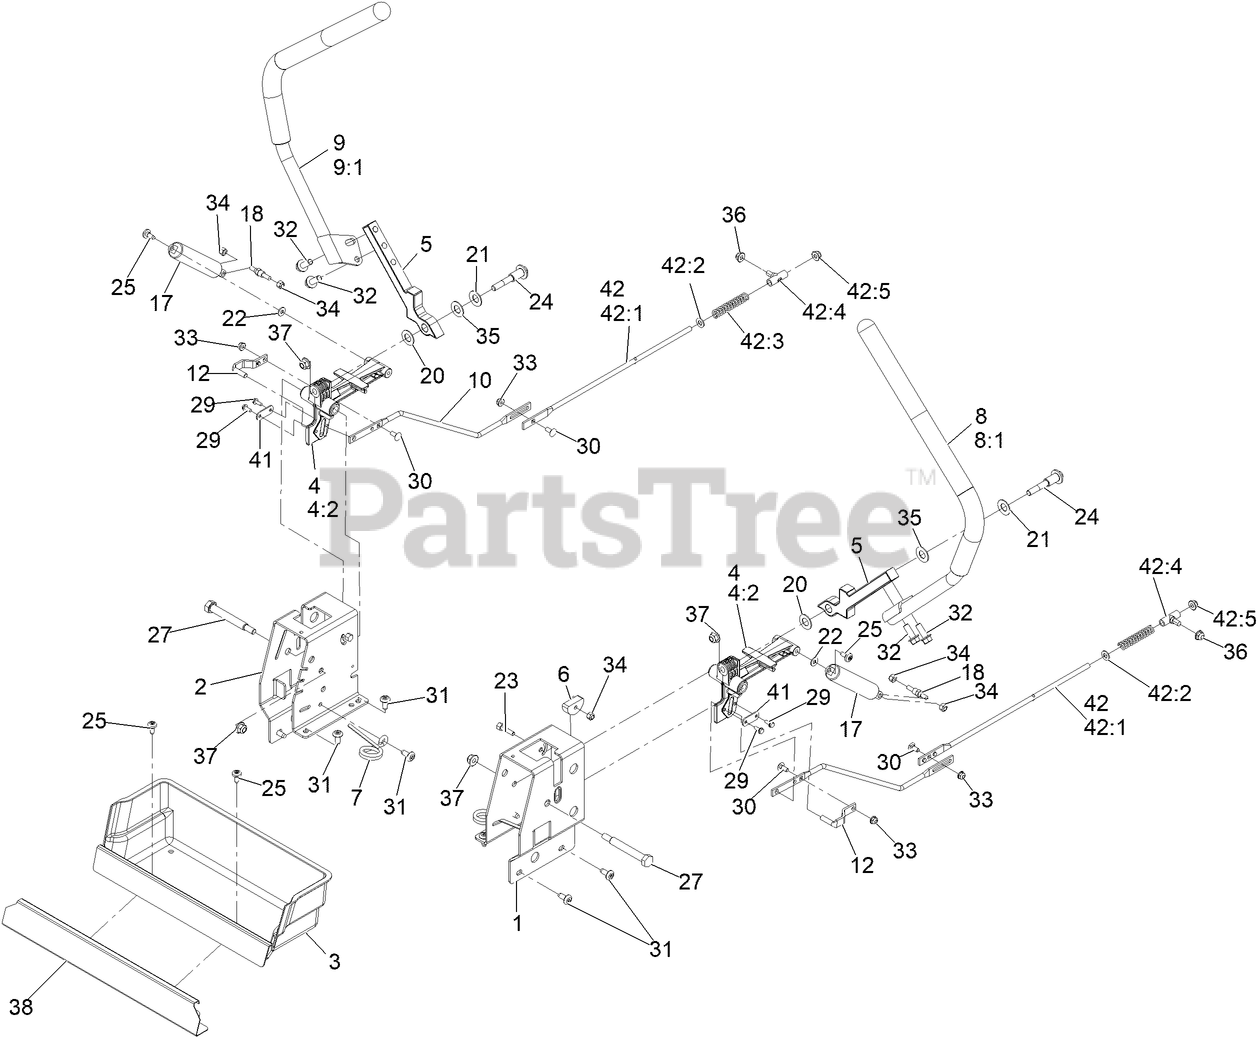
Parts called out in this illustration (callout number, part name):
1	PLATE-CONTROL BOX, LH
2	PLATE-CONTROL BOX, RH
3	BOX, STORAGE
4	ACTUATOR ARM ASM
4:2	BUSHING-FLANGE
5	ARM-CONTROL
6	ECCENTRIC
7	SPRING-TORSION
8	HANDLE-CONTROL, LH
9	HANDLE-CONTROL, RH
10	ROD-HYDRO, FRONT
12	PIN-ROD, HYDRO
17	DAMPER-NON CAVITATING
18	STUD-DAMPER
20	WASHER-NYLON
21	WASHER-BELLEVILLE
23	BOLT-PIVOT, ECCENTRIC
24	BOLT-PIVOT
25	SCREW-SHOULDER
27	BOLT-PIVOT
29	SCREW-TAPTITE
30	SCREW-CARR
32	SCREW-HHF 3/8-16 X 1
34	NUT-LOCK, NI
37	NUT-HF, NI
38	PLATE-KICK
41	PLATE-STOP, HYDRO
42	Rod Hydro ASM
42:1	ROD-HYDRO, REAR
42:2	WASHER-PLAIN
42:3	SPRING-COMPRESSION
42:4	Rod-Hydro
